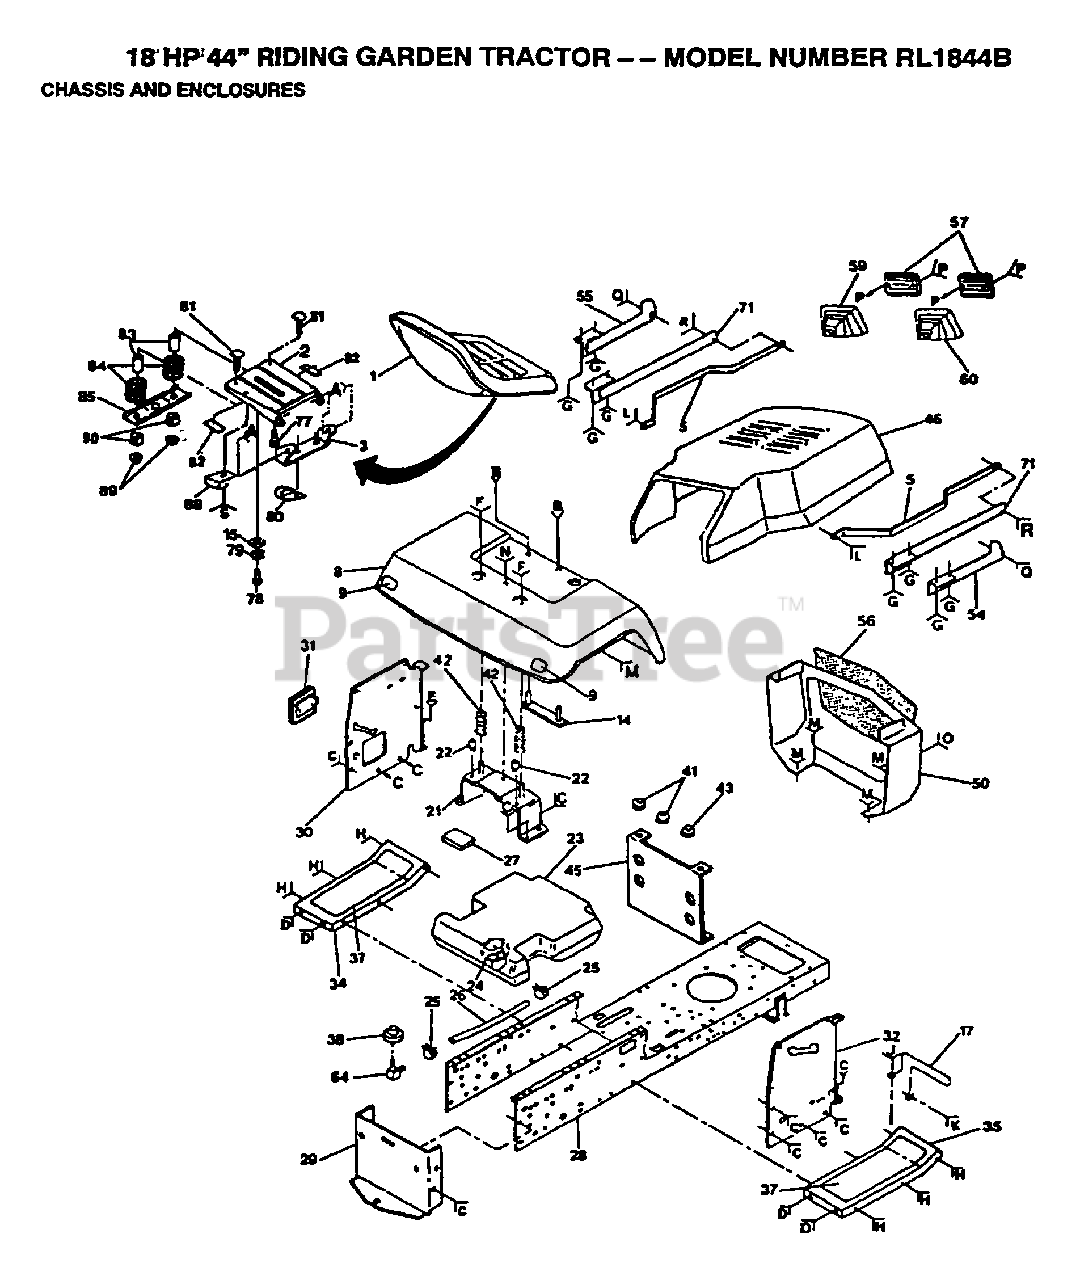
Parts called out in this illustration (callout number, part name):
9	REFLECTOR-TAIL YT
11	SCREW
12	WASHER
17	GUARD MUFFLER HYT
18	NUT
20	WASHER
22	NUT-PUSH YT
24	"BOLT,SHOULDER"
25	HOSE CLAMP
28	CHASSIS
29	DRAWBAR LT/YT
31	COVER ACCESS
32	PANEL DASH RH YT
33	BOLT LT
36	BOLT
37	"PAD,FOOTREST"
38	BUSHING OUTLET T
39	LOCKWASHER
41	SNAP BUSHING T
42	SPRING COMPRESSIO
49	SCREW LT
54	STRAP ASSY T
55	STRAP ASSY T
56	SCREEN GRILL GTV
63	BOLT
64	FUEL TANK STEM GT
66	SCREW GTV
67	WASHER HYT
68	WASHER
69	SCREW
71	STRAP ASSY-REAR T
73	BOLT T
75	"BOLT,SHOULDER"
77	"BOLT,SHOULDER"
78	BOLT
79	LOCKWASHER
80	CLIP T
81	BOLT
82	STRIP FORM
83	SPACER SPLIT
84	SPRING COMPRESSED
85	BRKT SWITCH
87	"NUT,KEPS"
90	BUSHING
